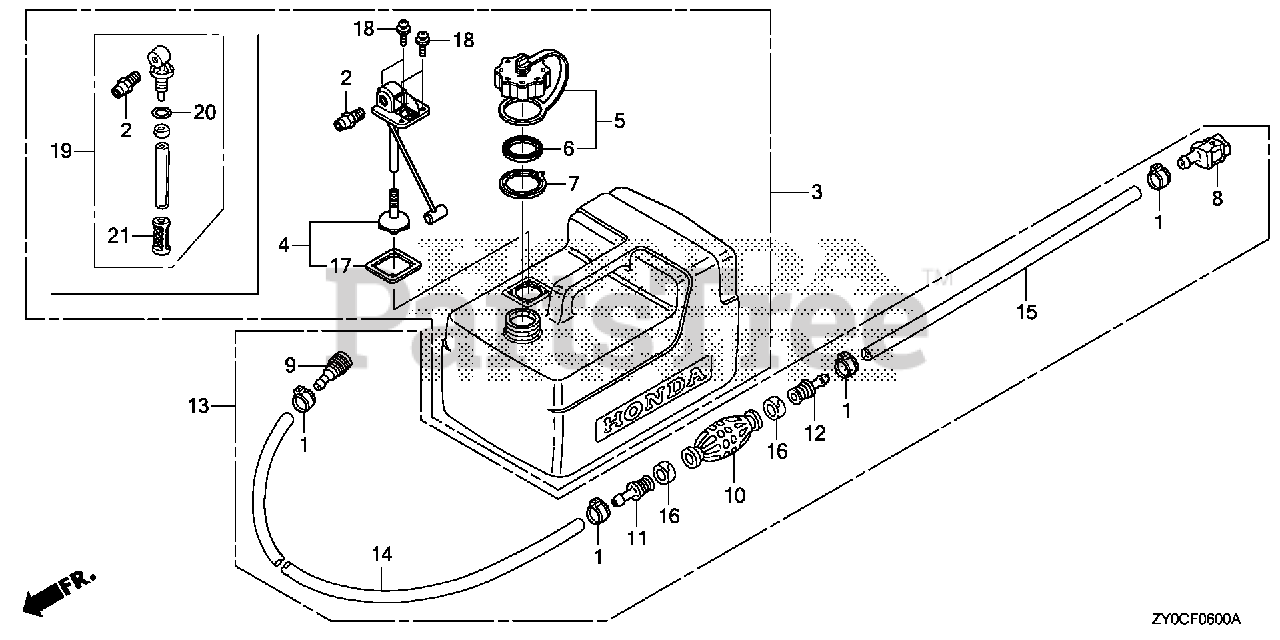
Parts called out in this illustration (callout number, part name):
1	CLAMP, FUEL TUBE (14.0) (CONNECTOR TYPE)
2	FITTING, QUICK DISCONNECT Use from Frame SN 1205705.
3	TANK, FUEL (12L)
4	FILTER KIT, FUEL
6	GASKET, FUEL CAP
7	RETAINER, PRESSURE RELIEF
8	CONNECTOR ASSY., FUEL (A)
9	CONNECTOR, FUEL (CONNECTOR TYPE)
10	BULB, PRIMER
11	VALVE, IN.
12	VALVE, OUTLET
13	TUBE ASSY., FUEL TANK
14	TUBE, FUEL LONG (7.3X2000)
15	TUBE, FUEL SHORT
16	BAND, TUBE CLIP (20MM)
17	GASKET, FUEL PICK-UP
18	BOLT-WASHER (5MM) (SEAL)
19	JOINT ASSY., FUEL
20	O-RING Use from Frame SN 1300962.
21	FILTER, FUEL
